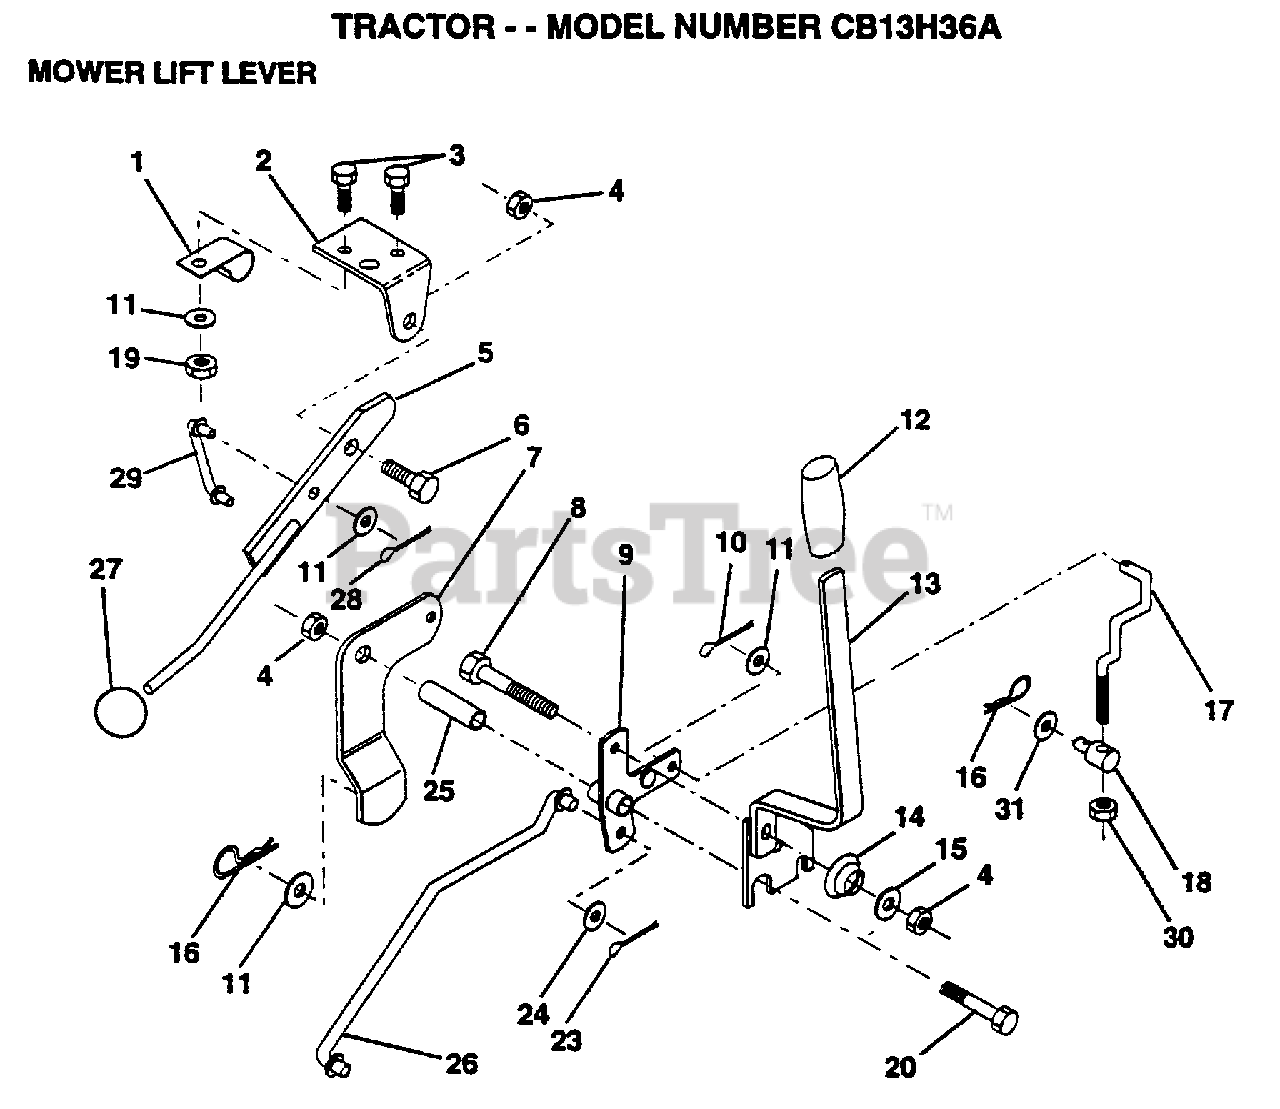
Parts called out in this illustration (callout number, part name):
1	"CLIP,INSULATOR"
2	BRKT CLUTCH
3	BOLT HXHD FIN
5	LEVER.ASM.CLUTCH
6	"BOLT, SHOULDER LT"
7	MWR CLUTCH ARM AS
8	BOLT
9	"BELLCRANK,LIFT"
10	COTTER PIN
11	WASHER
13	HANDLE.ASM.LIFT
14	SPRING COMPRESSIO
15	WASHER T
16	SPRING.RETAINER
17	"LINK,LIFT FRT"
18	TRUNION ADJ
20	BOLT
23	PIN COTTER 1/8
25	TUBE SPACER
26	ROD LIFT MOWER
27	KNOB T(3/8 HOLE)
29	CLUTCH LINK
30	NUT
31	WASHER
